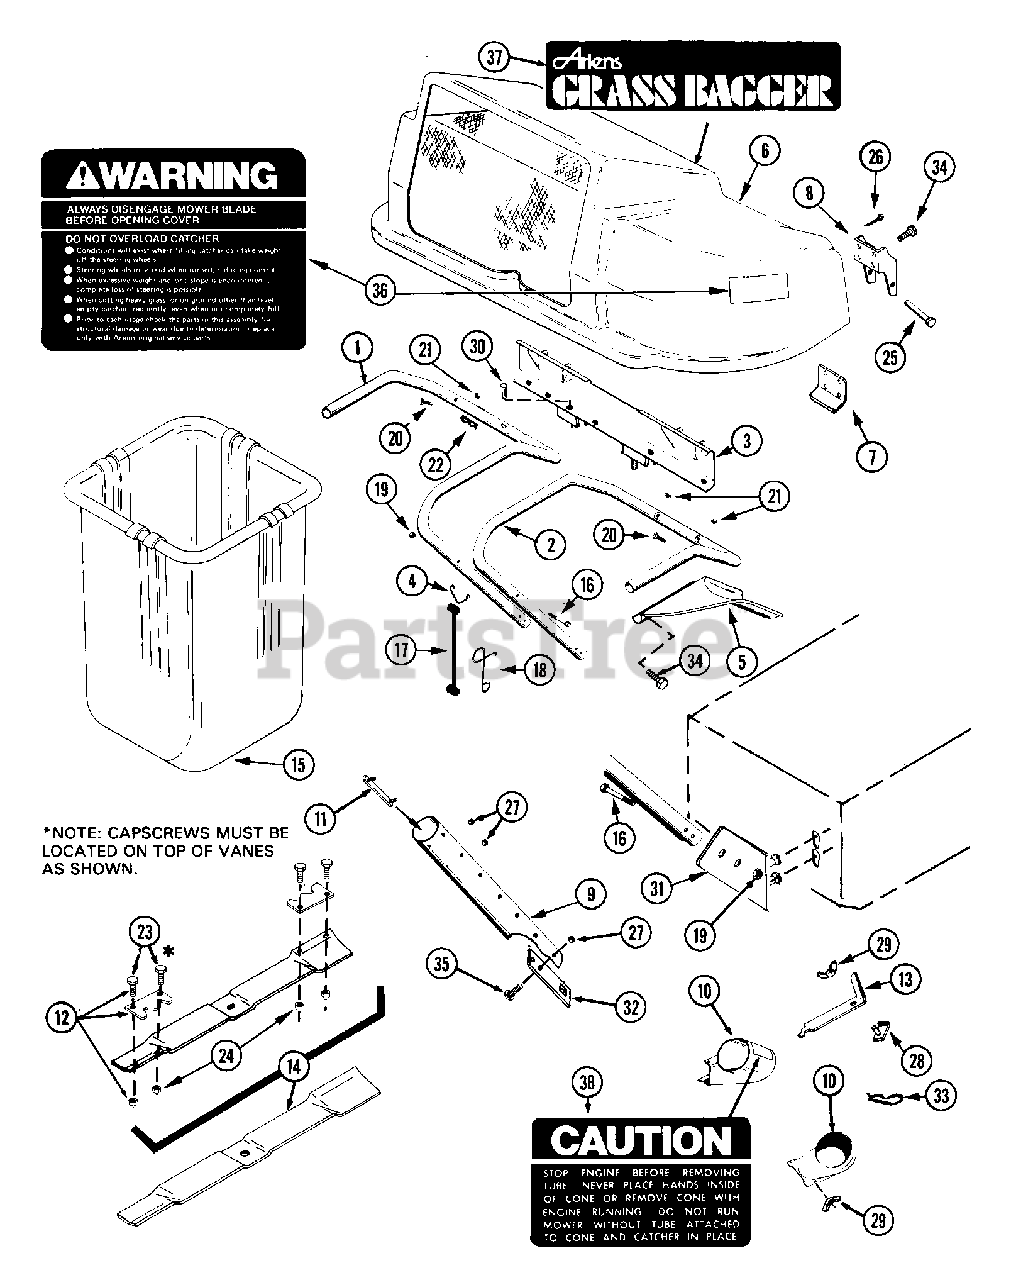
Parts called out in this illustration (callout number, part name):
1	TUBE L.H. SUPPORT
2	TUBE R.H. SUPPORT
5	SUPPORT TUBE
6	GRASS CATCHER COVER ASSEMBLY
7	RETAINER
9	TUBE BLANK
10	GRASS CATCHER BOOT ASSEMBLY
13	STRAP CONE
14	MOWER BLADE
16	BLT-HEX .25-20X2.25 GR2
17	BATTERY STRAP
18	HOOK
19	NUT-LK-CTR .250-20 PL
20	SCR-MCH .31-18X1.50 CROVCNTRS
21	NUT-LK-NYL.312-18 PL
22	PIN-HAIR INT .08X.38X1.42 YWZC
25	CLEVIS PIN
26	PIN-COTR .06X.50
27	NUT-LK-FLG .250-20 PL
28	CLIP CONE
29	NUT-WING W/INSERT .312 - 18
30	CLEVIS PIN
31	BRACKET MOUNTING
32	STRAP
33	PIN-HAIR INT .09X.188 PL
34	BLT-SCRHFWH .25-20X.62 PL
35	BLT-RDHDSQNK .25-20X.50 SHT PL
36	WARNING DECAL
37	ARIENS GRASS BAGGER DECAL
38	CAUTION DECAL
